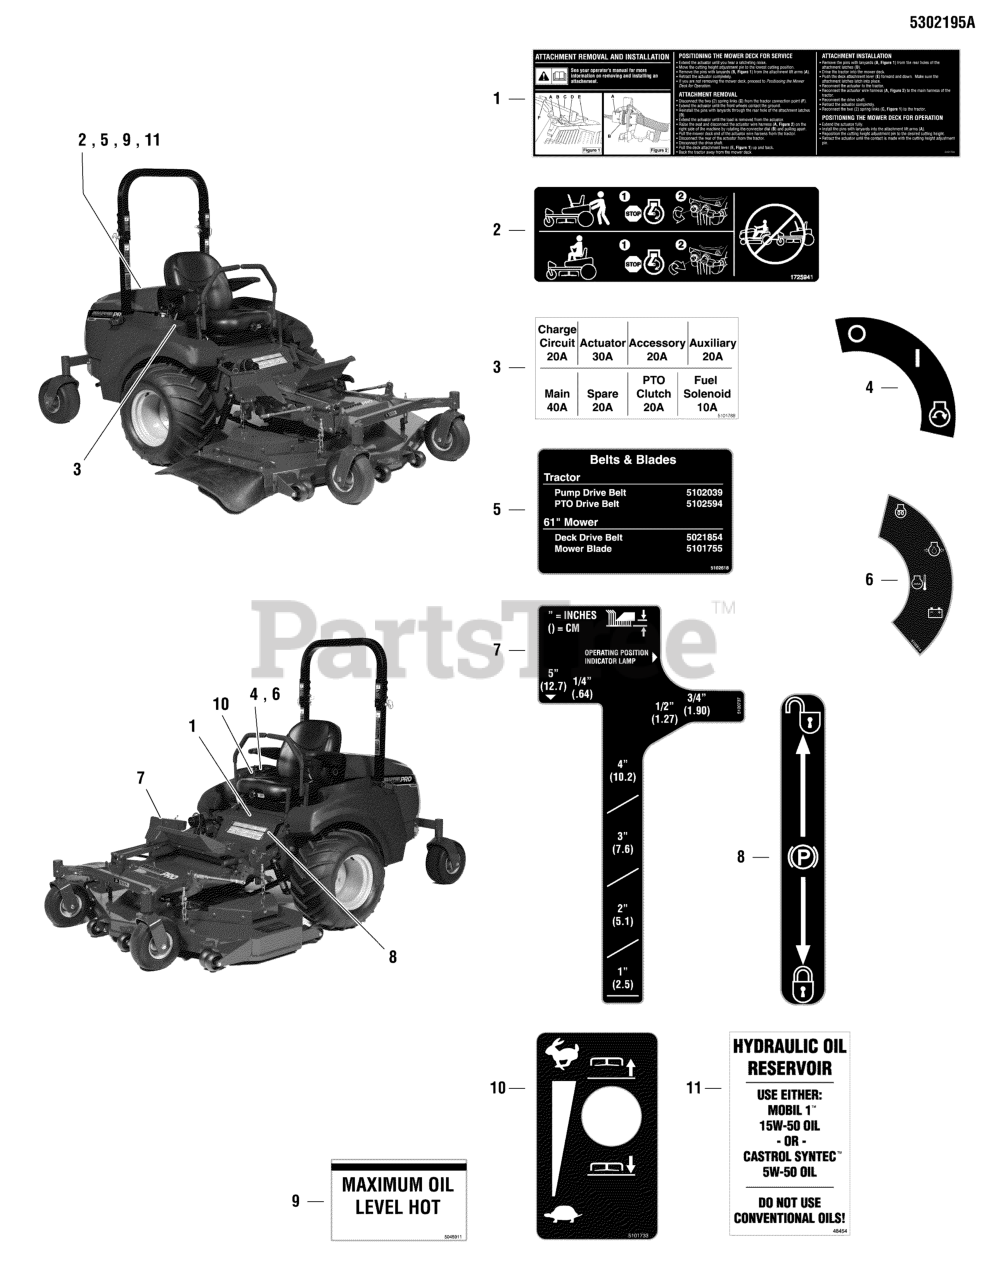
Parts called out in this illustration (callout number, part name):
1	DECAL, ATTACHMENT, S800X
2	DECAL, CZT HYRDO RELEASE
3	DECAL, FUSE LOCATION, S800X
4	DECAL, IGNITION SWITCH
5	DECAL, BELT & BLADE, S800XY30D-72
6	DECAL, WARNING LAMPS, S800XY
7	DECAL, DECK HEIGHT, OUT FRONT MOWER
8	DECAL, PARKING BRAKE SYMBOLS
9	DECAL, MAX OIL LEVEL
10	DECAL, CONTROL PANEL, S800X
11	DECAL, OIL RESEVOIR
